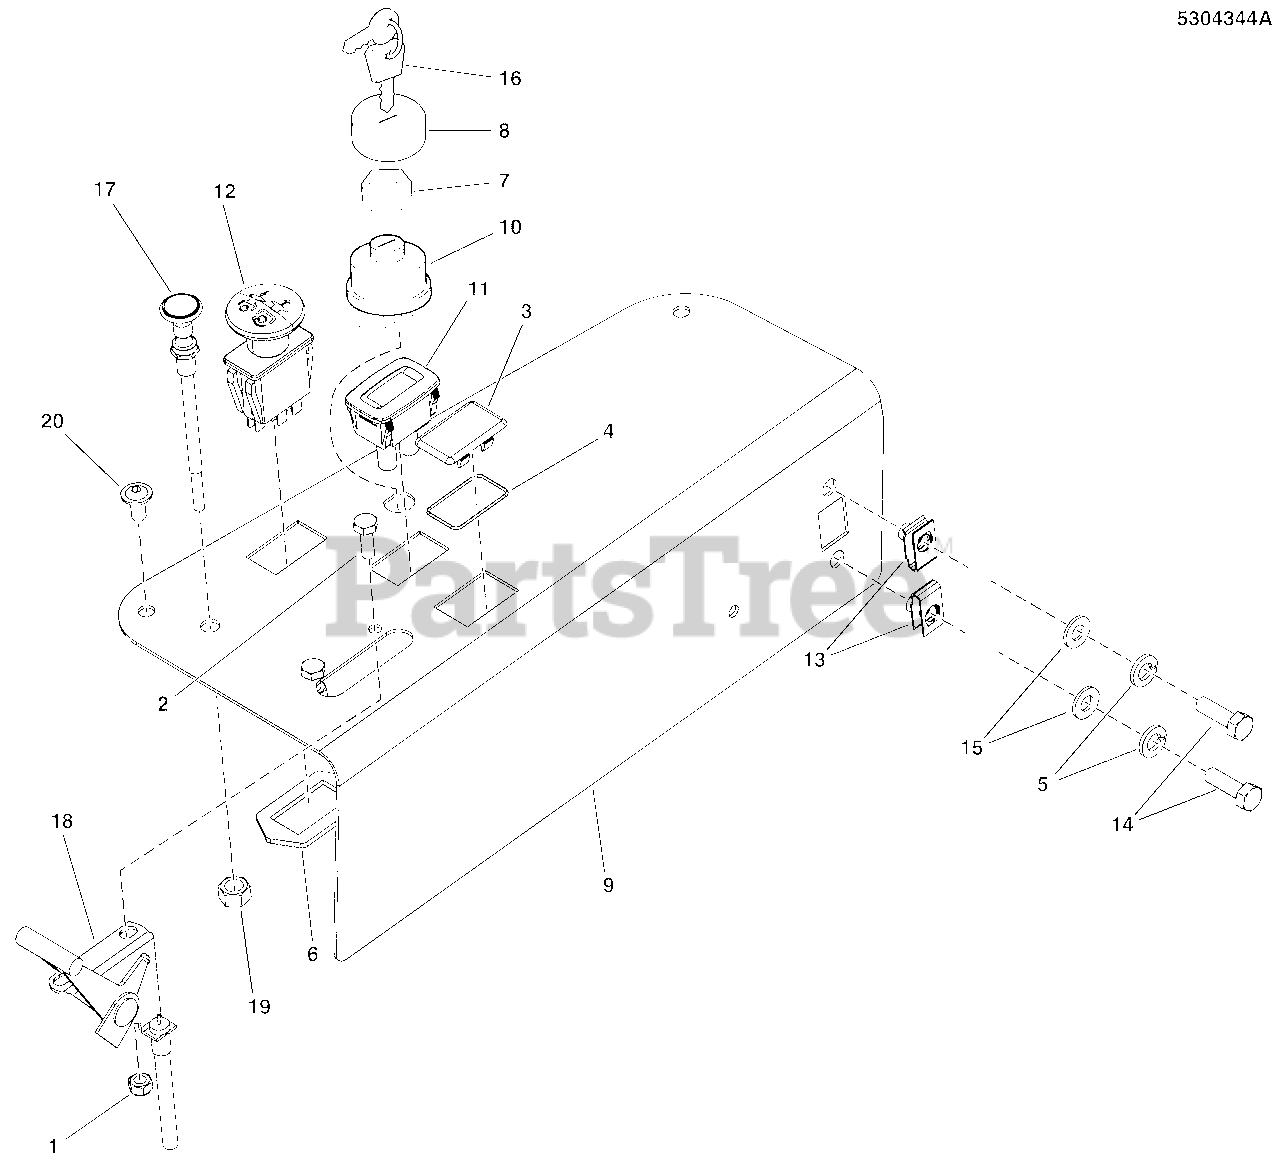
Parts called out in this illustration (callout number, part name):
1	NUT, Hex, Nylon Lock, 1/4-20
2	CAPSCREW, Hex Head, 1/4-20 x 3/4 (stiffener to top of cover)
3	PLUG, Hole, Electric Lift (Hydro models only)
4	O-RING, 7/8" ID X 1/16" W
5	WASHER, Flat
6	RING, SWITCH RETAINER, PTO
7	NUT, Hex Flange, 5/8-32 IGN SW DIE CAST
8	COVER, Ignition Switch
9	PLATE, CONTROL PANEL, S550 - BLK
10	SWITCH ASSEMBLY, Ignition Indak No Keys/Hdwr
11	HOUR METER, ASSEMBLE
12	SWITCH, PTO Push/Pull, Yel Knob w/Symbols, 8 Terminal
13	CLIP, BODY , 5/16-18 FOR 7 GA.
14	CAPSCREW, Hex Head, 5/16-18 X 1
15	WASHER, 5/16
16	KEYS, Ignition
17	CABLE, CHOKE CONTROL, 51 (Z)
18	CABLE, Throttle Control, 40"
19	NUT, 3/8-24 HEX JAM (SV)
20	SCREW, #10-24 X 3/4", ROUND PHILLIPS
